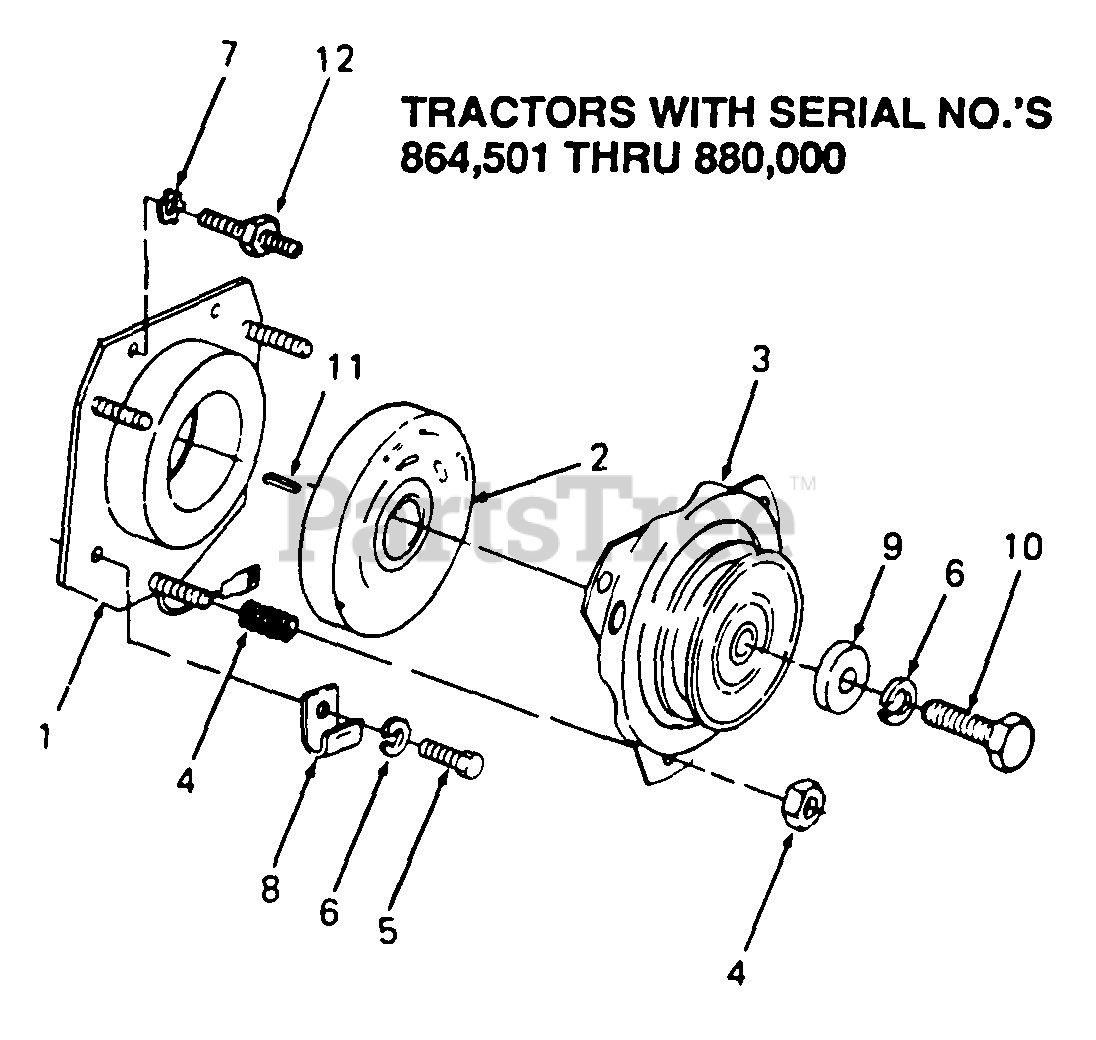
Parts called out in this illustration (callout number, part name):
4	Spring & Nut Kit
5	Screw, Hex Cap, 7/16-14 x .75 Lg GR5
6	Washer, Lock, 7/16
7	Washer, Ext Lock, .45 x .75 x .035 Thk
8	Clamp, Cable
9	Washer, Flat, .47 x 1.5 x .225 Thk
10	Screw, Hex Cap, 7/16-20 x 1.50 Lg GR5
11	Key, Square, 1/4 x .75 Lg
12	Stud, 7/16-14 Trd
